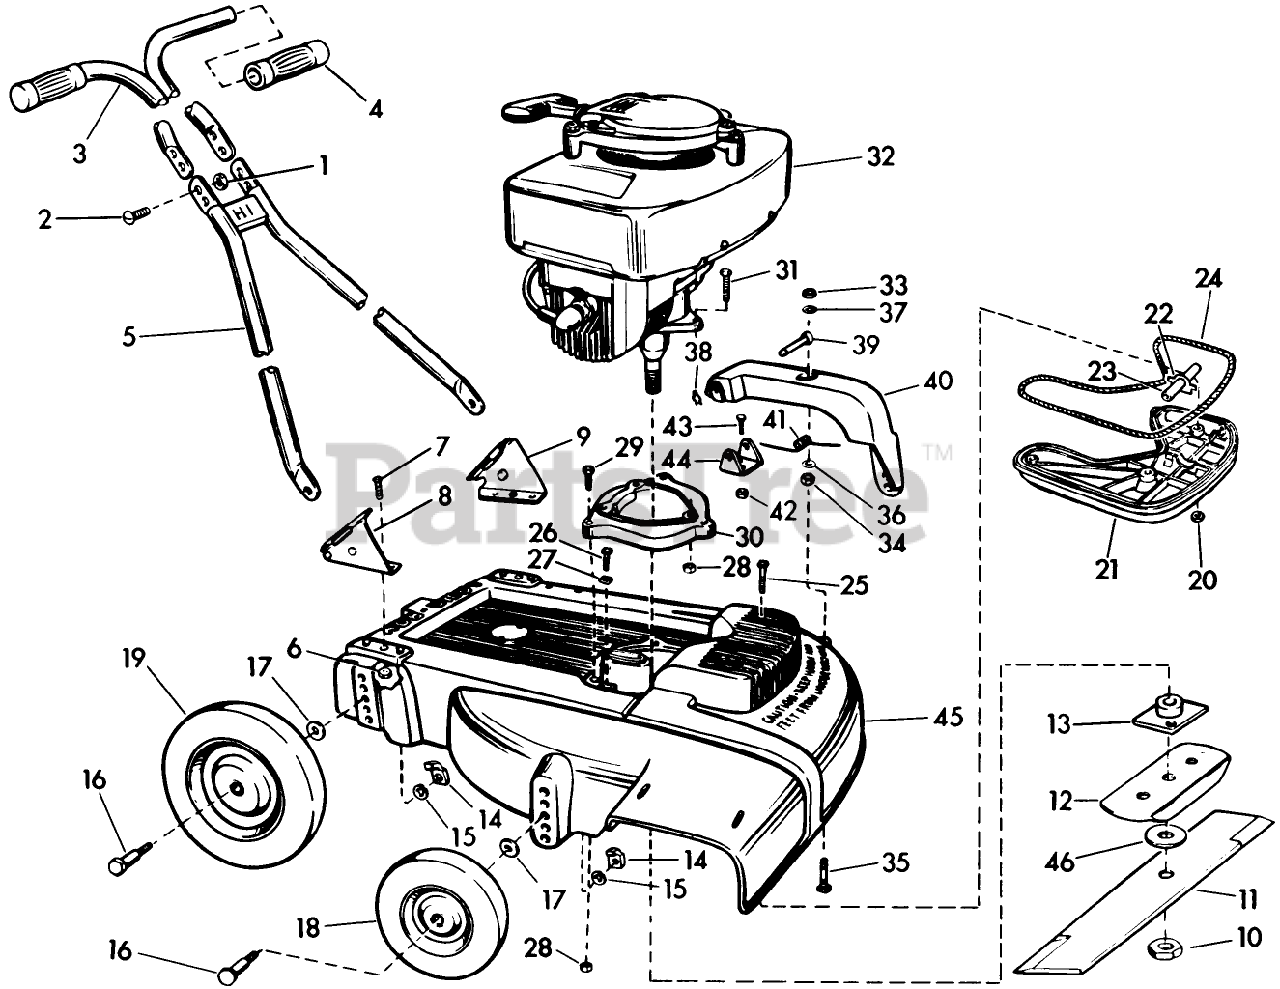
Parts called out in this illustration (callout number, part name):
1	STOP NUT
10	NUT-BLADE
11	Blade-21"
13	PLATE AND COLLAR ASM
15	WASHER, LOCK
20	LOCKNUT E
21	Muffler
22	Gasket-Internal Tube
23	Tube-Internal Muffler
26	Bolt-Muffler
27	Gasket-Muffler Bolt
29	Screw-Sub Base Mounting
30	Sub Base
33	STOP NUT
34	Jam Nut
35	Bolt-Level-Ride Arm
36	Washer-Level Ride Arm
37	Washer-Level Ride, Fiber
38	Hair Pin-Level Ride Arm
39	Pin-Level Ride Arm
40	Arm-Level Ride
41	Spring-Level-Ride Arm
42	STOP NUT
43	Screw-Level-RideArm Bracket
44	Bracket-Level Ride Arm
45	Housing-18" Model 5210
45	Housing-21" Model 7210
